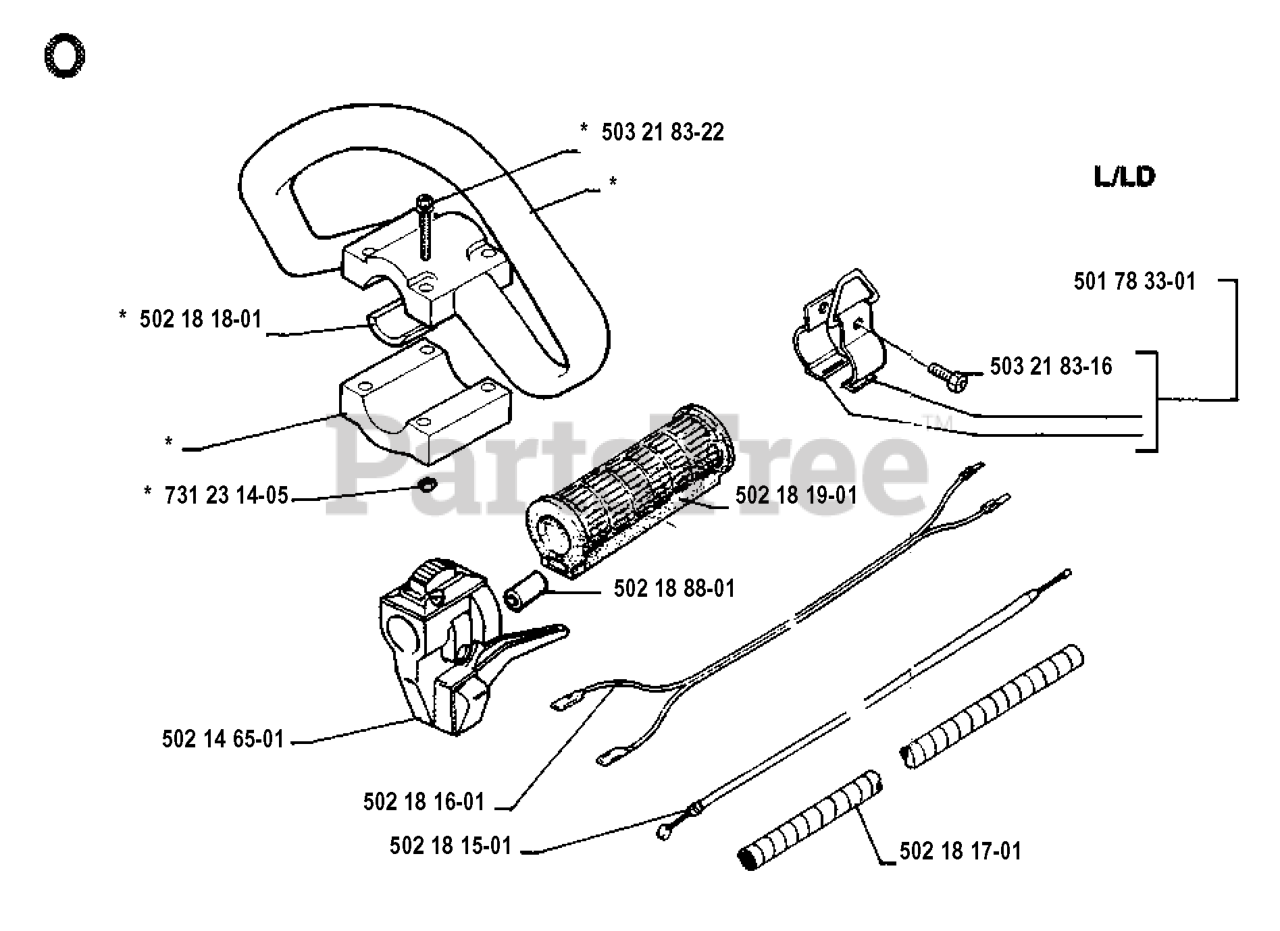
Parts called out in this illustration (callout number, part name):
1	LOWER HOUSING
2	HOUSING UPPER 70255
3	SEAL.LIP.H-G.(9008000-0128)
4	RING RETAINING 2003016
5	RING.RETAINING.(2003052)
6	BALL BEARING
7	CRADLE BEARING
8	BEARING, THRUST 50551
9	SWASHPLATE (2003087)
13	BLOCK, CYL ASSY
14	TRUNNION ARM
17	SLOT GUIDE
18	SHAFT, MOTOR
19	BEARING, THRUST 50552
23	BLOCK, CYL ASSY
25	BYPASS ACTUATOR
26	CENTER SECTION ASS'Y KIT
28	RETAINING RING
34	ELEMENT, OIL FILTER
35	BYPASS ARM
36	RETAINING RING 44870
37	ACTUATING ARM
38	ACTUATING PIN 44891
39	BOLT 5/16-24 X 1-3/4
40	LOCKNUT, HEX 5/16-24
41	BRAKE ROTOR 70135 HYDRO-GEAR
43	WASHER .34X.88X.06.44130
44	KIT SVC DIFFRENTIAL 70130
52	WASHER.HYDRO-GEAR 44875
53	SEAL.HYDRO.53901
56	SHAFT.INPUT.50005
58	BOLT #44876
62	CONTROL ARM 50254
63	DAMPENER PUCK
64	SCREW.SET.50018
68	SPRING HELICAL COMP 50277
69	STUD 5/16-24 50284
83	JACK SHAFT ASSY
89	WASHER 50132
90	SLEEVE.BEARING 50118
91	RP SEAL, WIPER
92	SPRING 2003014
113	CAP, VENT ASSY
114	O-RING KIT 70110
119	SPACER.HYDRO GEAR 50278
134	NUT.CAS.HYD.44142
135	ID DOT HYDD
139	SPRING, COMPRESSION 50431
140	NUT, HEX 5/16-24
